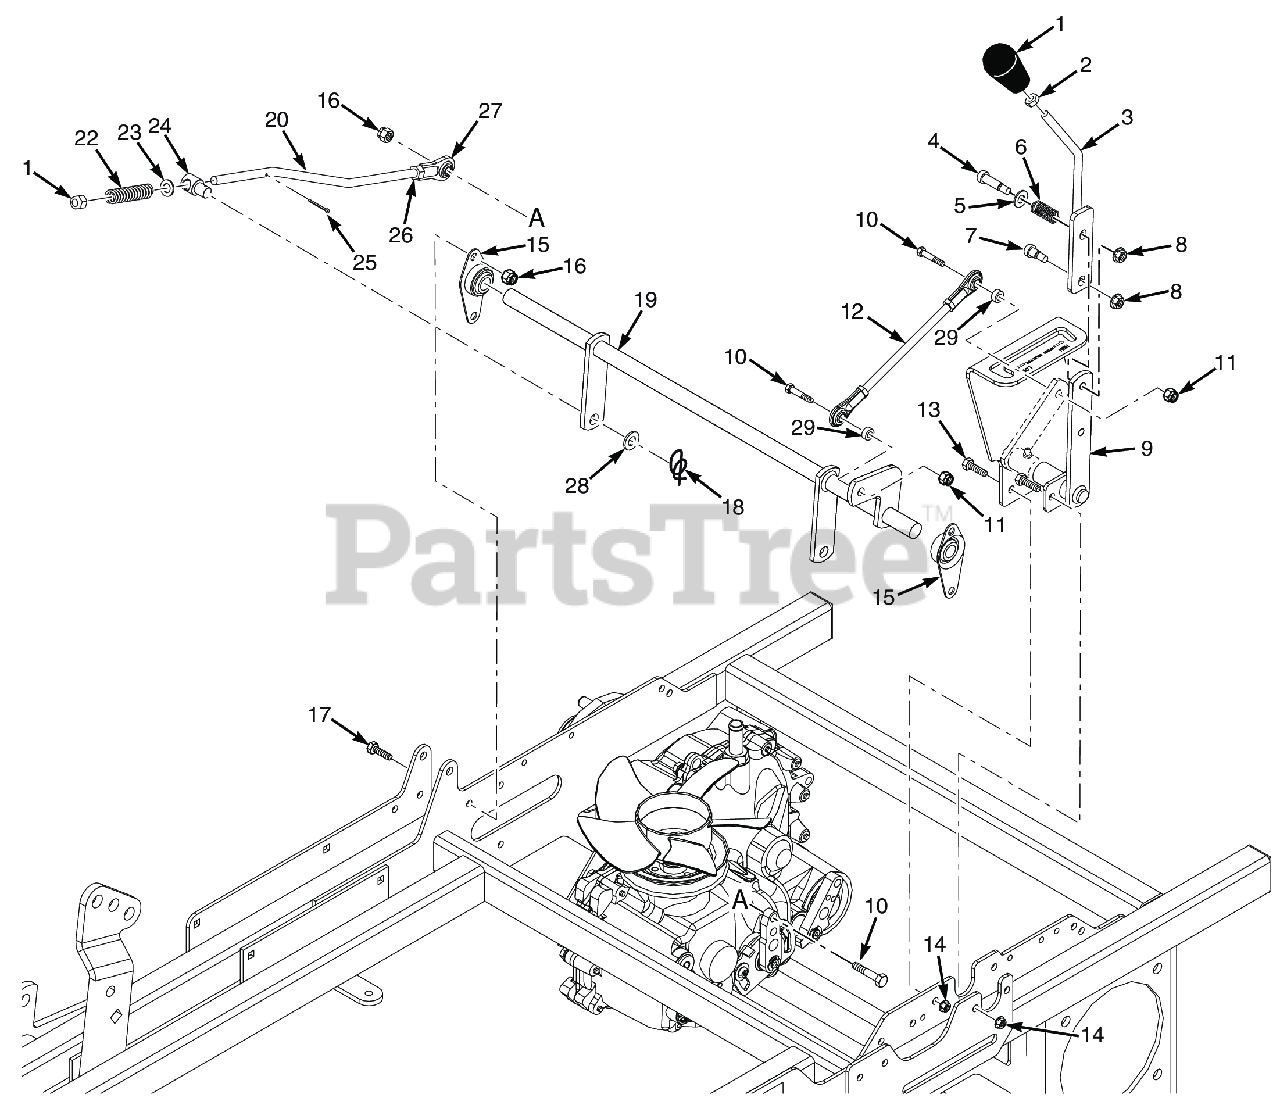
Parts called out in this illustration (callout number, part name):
1	Knob, Soft Touch
2	HEX NUT, JAM 3/8-16
3	LEVER WLMT, SPD CONTROL
4	Bolt, Shoulder 3/8 x 1"
5	Flatwasher, 3/8 (.406 x .812 x .065)
6	Spring, Speed Control Slide
7	Bolt, Shoulder 3/8 x .375"
8	Nut, Serrated Flange 5/16-18 (Right Front Engine Mounting, Briggs and Kohler Only)
9	Control Weldment, Speed Range Adjust
9	GREASE FITTING, STR. 1/4-28 SELF TAP.
10	Bolt, Hex Head, 3/8-16 x 1-1/2"
11	HEX NUT, ELASTIC STOP LOCK, 3/8-16
12	Linkage Assembly, Upper Speed Control
12	Rod End, 3/8-24 UNF RH
12	Nut, 3/8-24 UNF R.H. Thread
12	Rod End, 3/8-24 UNF LH
12	Nut, 3/8-24 UNF-2B LH Thread
13	Bolt, Heax Head 5/16-18 x 1" (48V / 52V)
14	Nut, Flange Head Elastic Stop 5/16-18
15	Bearing, Self Align
16	Nut, Flange Head Elastic Stop 5/16-18
17	BOLT, SERRATED FLANGE HEX HEAD 5/16-18 X 3/4"
18	Pin, Rue Cotter 1/2" Dia.
19	Speed Control Bellcrank Weldment
20	ROD, BRAKE LINKAGE
21	Nut, Elastic Stop 3/8-16, grade 8 black
22	Spring, Brake
23	Flatwasher, 3/8-.406 x .734 x .063
24	BUSHING, PIVOT SLIDE
25	COTTER PIN, 3/32 X 1"
26	HEX NUT, 3/8-24 R.H. THREAD
27	Rod End, 3/8-24
28	Flatwasher, 3/8 (.391 x .938 x .105 HD) Grade 8
29	SPACER, IDLER
